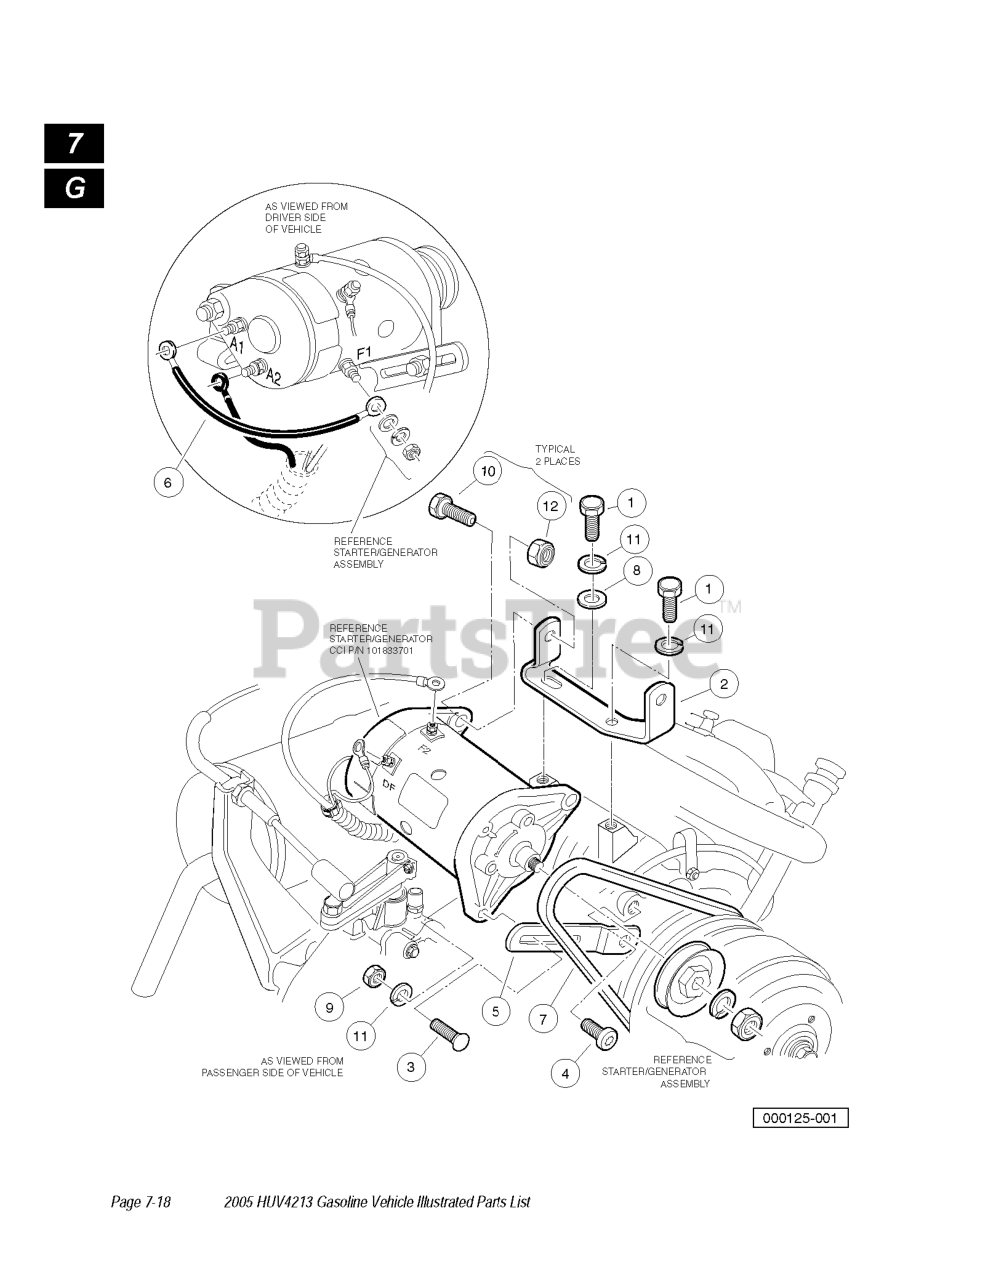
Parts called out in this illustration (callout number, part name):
1	SCREW, M8-125 X 22 HEX GR.8.8
2	BRACKET, FE350 S/G MOUNTING
3	BOLT, 5/16-18 RD HD SQ NECK
4	SCREW, M8-1.25 X 18MM TORX
5	BRACKET, S/G-ADJUSTABLE
6	WIRE ASSY, #6 GREEN
7	BELT, STARTER-GENERATOR
8	WASHER, 5/16 TYPE A FLAT
9	NUT, 5/16-18 HEX
11	LOCKWASHER, 5/16 SPLIT
12	LOCKNUT, 3/8-16 HEX
